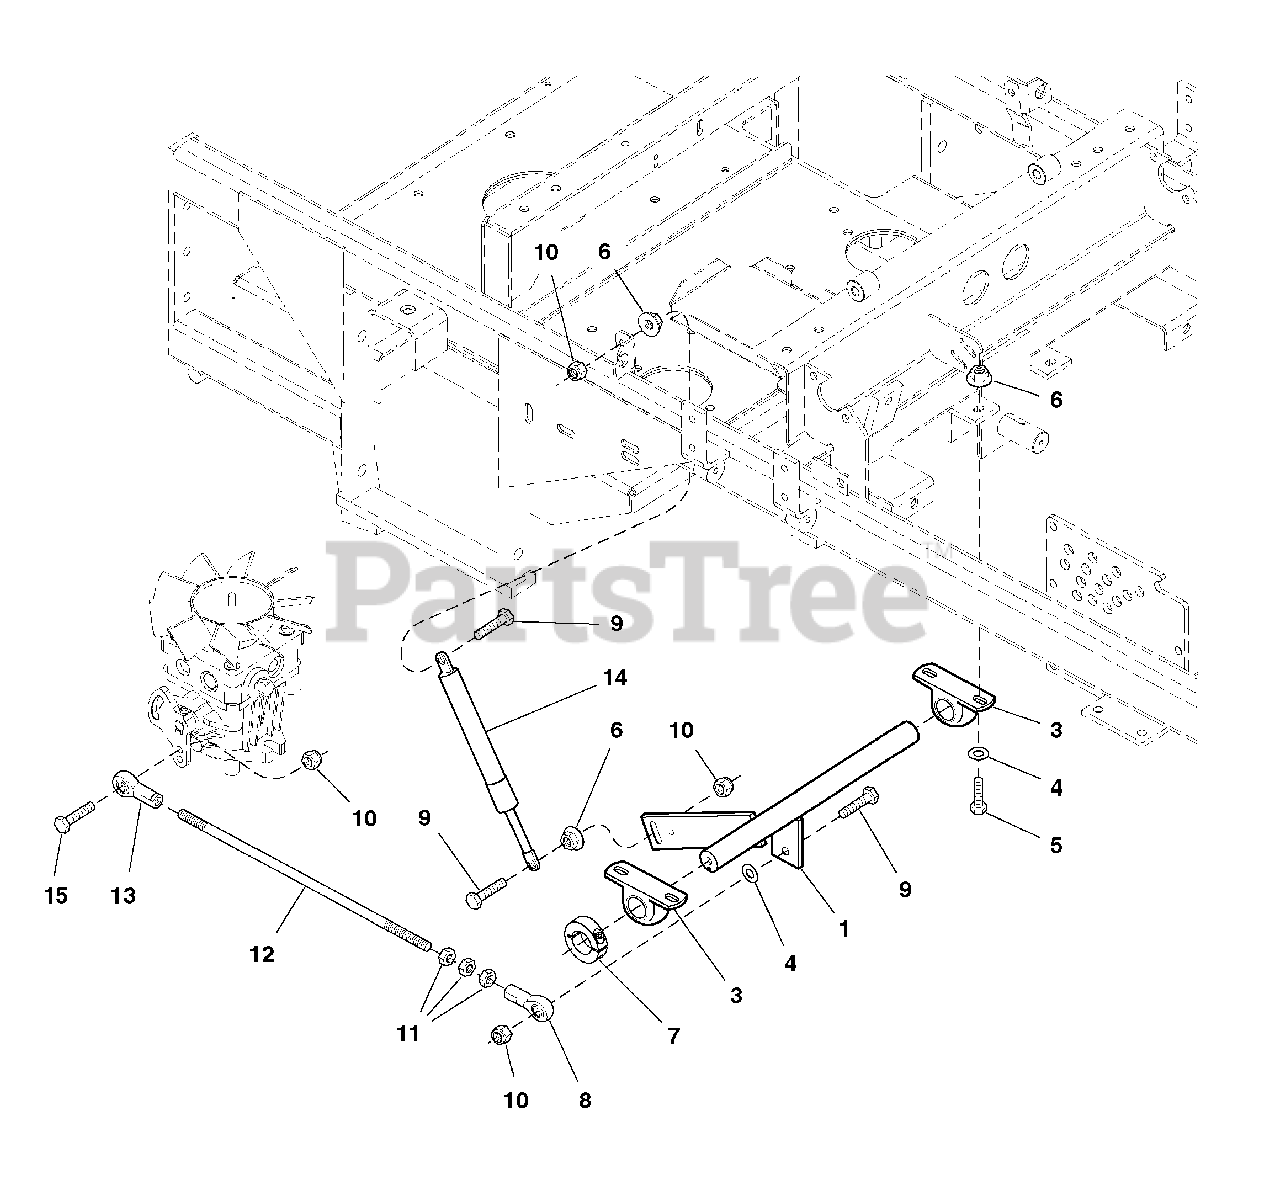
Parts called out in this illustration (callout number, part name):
1	CONTROL SHAFT-RH
3	BEARING, Pillow Block
4	WASHER, 5/16
5	CAPSCREW, Hex Hd, 5/16-18 x 1
6	NUT, Hex, Serrated Flange, 5/16-18
7	COLLAR, 1" Split
8	BALL JOINT 5/16-24 RH FEMALE STAMPED STL
9	CAPSCREW, Hex Hd, 5/16-18 x 1-1/4
10	NUT, Hex, Nylon Lock, 5/16-18
11	NUT, Hex, 5/16-24
12	HYDRO LINKAGE ROD
13	BALL JOINT 5/16-24 LH FEMALE STAMPED STL
14	DAMPENER
15	CAPSCREW, Hex Hd, 5/16-18 x 1-1/8
